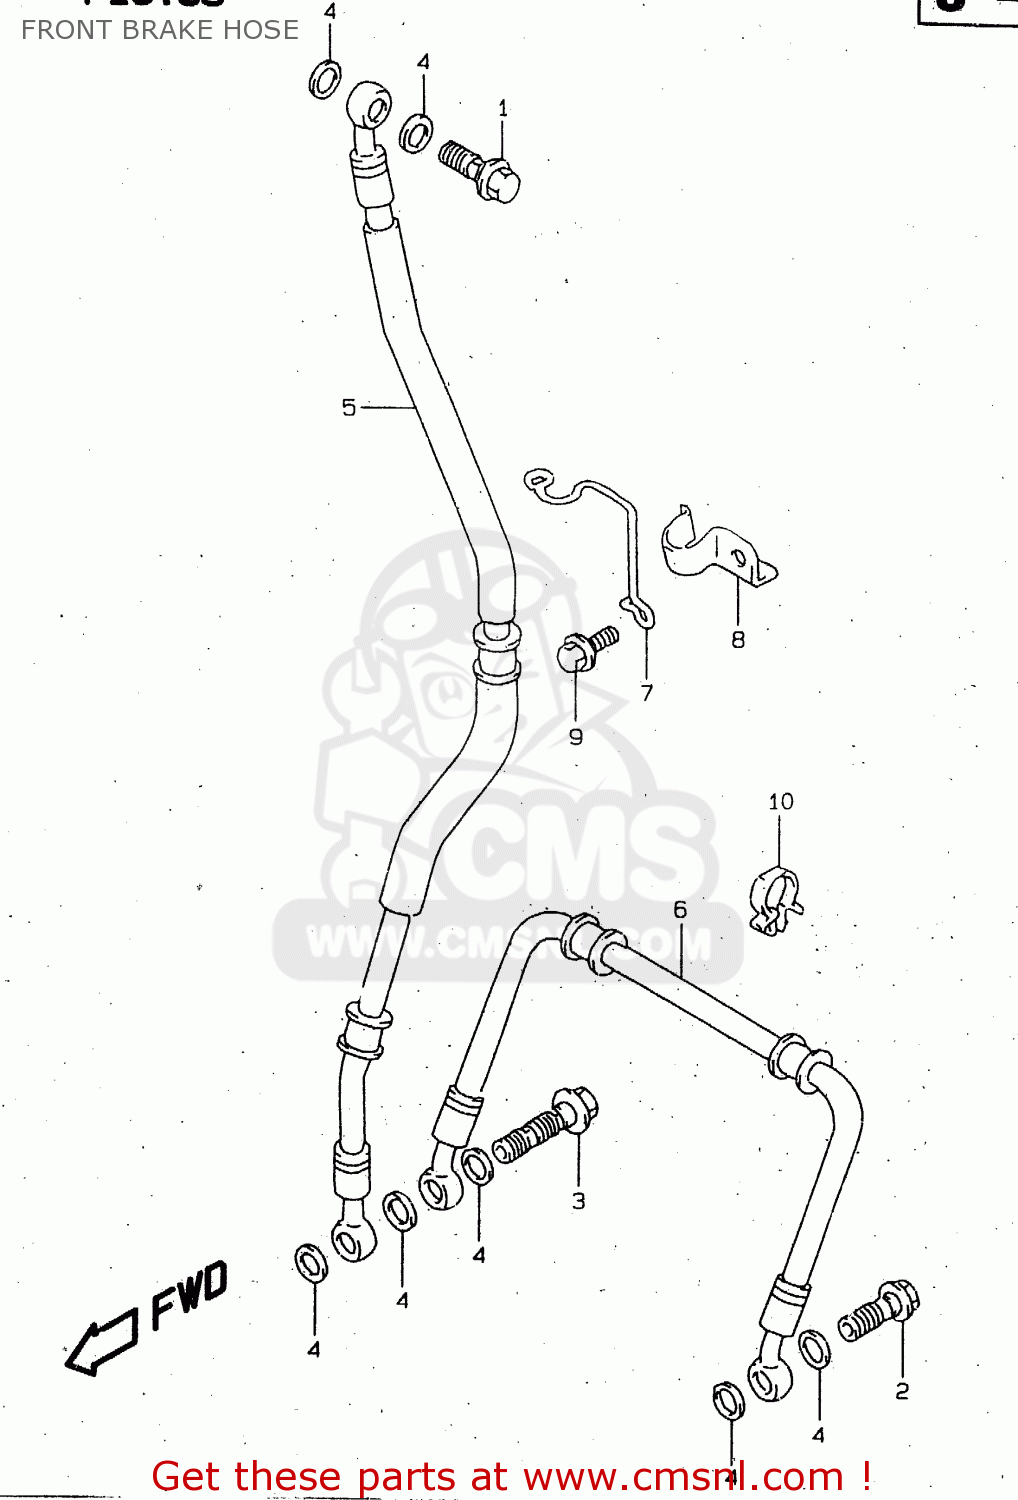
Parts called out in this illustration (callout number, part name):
1	BOLT UNION
2	BOLT UNION
3	BOLT UNION
4	WASHER(10X15X1.5)
5	HOSE,FR BRAKE NO.1
6	HOSE,FR BRAKE NO.2
7	GUIDE,FRONT BRAKE HOSE
8	CLAMP,FR BRAKE HOSE UPR
9	BOLT
10	CLAMP
